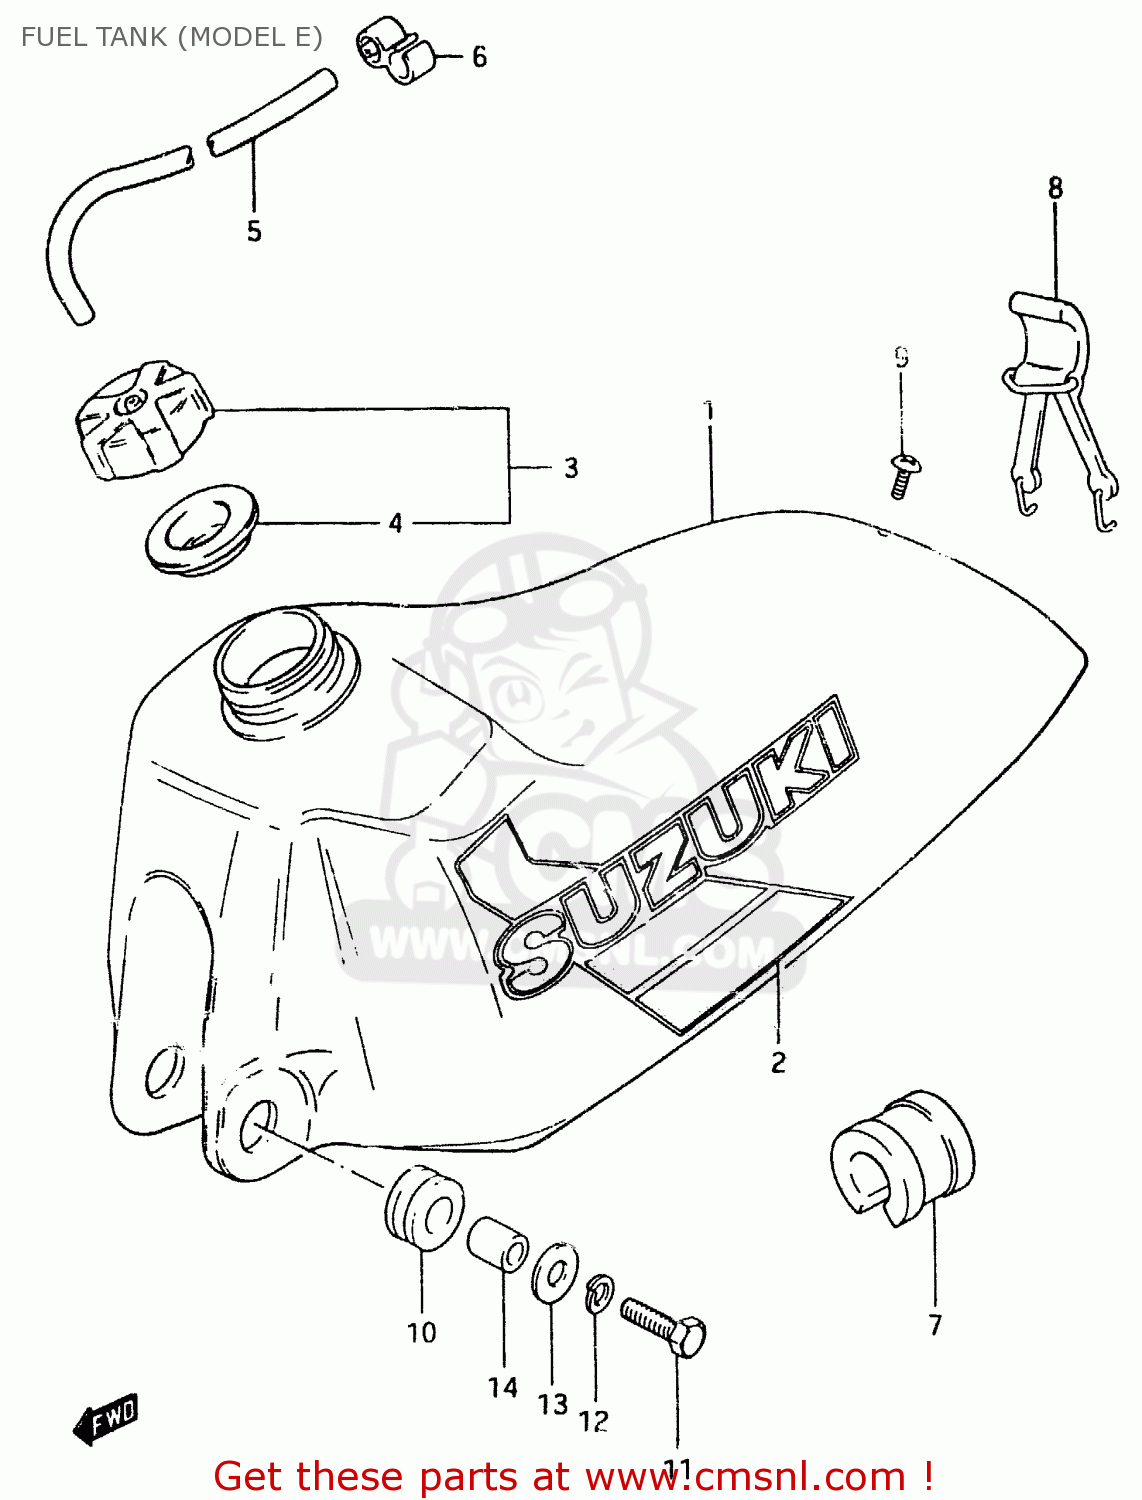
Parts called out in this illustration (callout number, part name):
1	TANK ASSEMBLY,FUEL
2	TAPE SET,FUEL TANK
3	CAP SET,FUEL TANK
4	GASKET,FUEL TANK CAP (NAS)
5	HOSE
6	CLAMP,BREATHER HOSE
7	CUSHION,FUEL TANK UPR
8	BAND,FUEL TANK,REAR
9	SCREW (6X15)
10	CUSHION
11	BOLT (8X30)
12	LOCK WASHER
13	WASHER (8.5X26X1.2)
14	SPACER (8.8X12X13.5)
